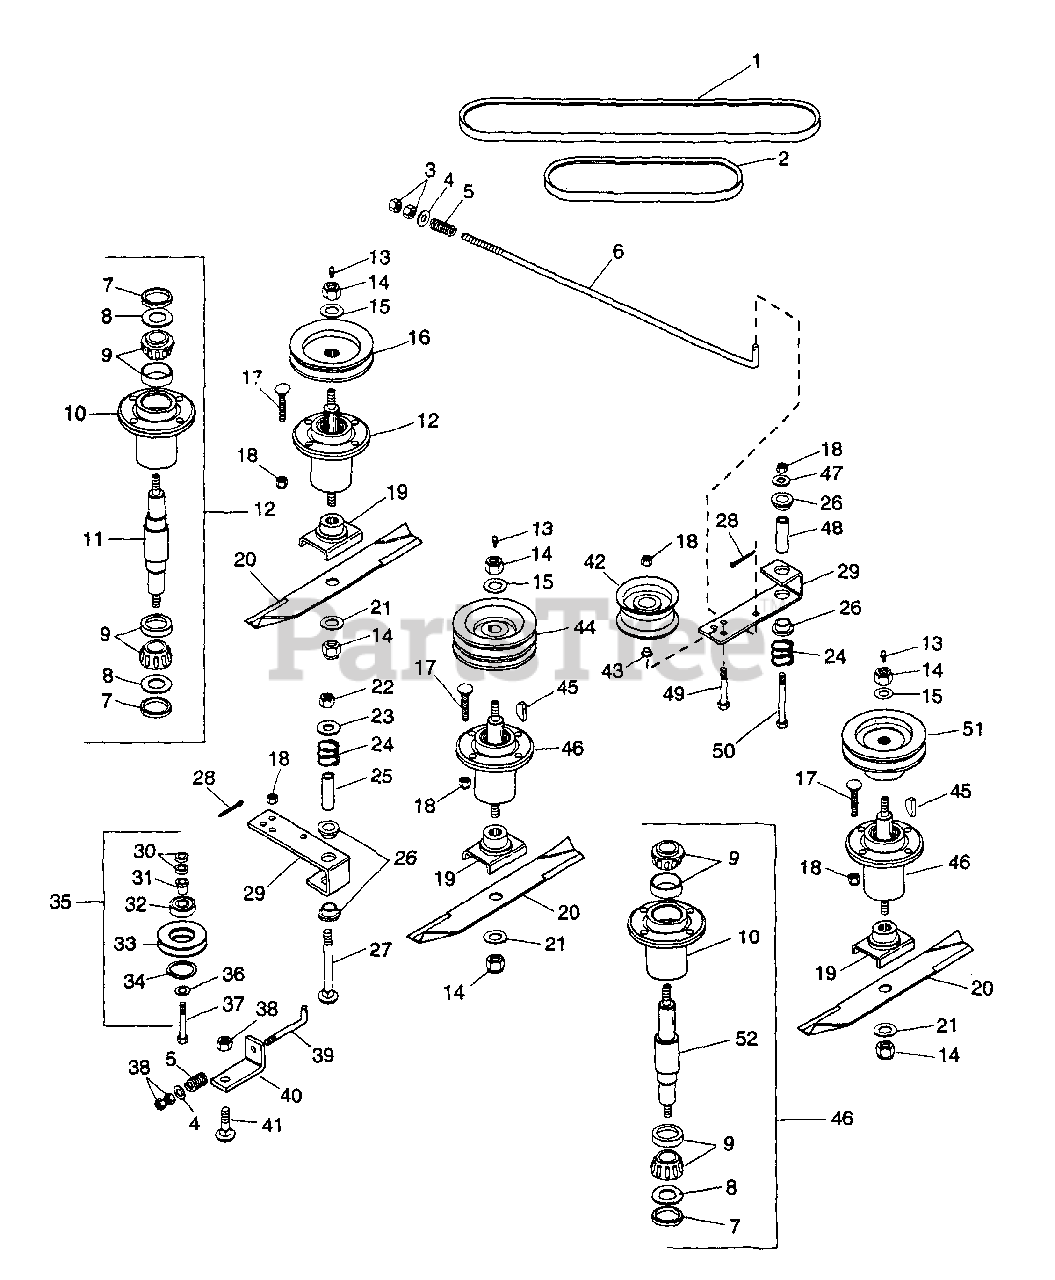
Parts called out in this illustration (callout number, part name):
1	V-Belt A-RMA 48.00 x .516/.031
2	V-Belt A-RMA 40.60 x .516/.031
3	Nut-Hex .375-16
4	Washer-Flat-Steel .281 x .625 x .065
5	Spring-Compression .188 x 1.66 x 2.0
6	Rod, Idler 25.0 Long
7	Seal-Steel
8	Washer-Flat-Steel .97 x 1.865 x .03
9	Assembly, Bearing Cup & Cone
10	Housing, Bearing
11	Shaft, Spindle
12	Spindle, Assembly
13	Fitting, Lube 1/8
14	Nut, Lock 5/8-11 Hex W/Insr
15	Washer-Flat-Steel .687 x 1.312 x .135
16	Sheave, Spindle
17	Bolt-Carriage .38-16 x 1.375
18	Nut-Lock-Nylon .375-16 Pl
19	Weldment, Blade Cradle
20	Blade
21	Washer-Flat-Steel .656 x 1.312 x .095 Pl
22	Nut-Lock .50-13 Hex Type N
23	Washer-Flat-Steel .531 x 1.250 x .100
24	Spring-Compression
25	Bushing, Steel .560 x .750 x 2.44
26	Bushing-Flange .762 x 1.0 x .580 x 1.48 NY
27	Bolt-Carriage .50-13 x 3.50
28	Pin-Cotter .09 x .75 Pl
29	Arm, Idler Pivot
30	Bushing .406 x .750 x .188
31	Bushing-Flange .786 x 1.0 x .79
32	Bearing-Ball 1.85 x .787 x .55
33	Sheave Idler
34	Snap Ring - Internal 2.054 x .062
35	Assembly, Idler Sheave
36	Washer, Flat .375 x 1.125 x .065
37	Bolt-Hex .38-16 x 2.00 Pl Gr. 5
38	Nut-Lock-Nylon .312-19 Pl
39	Rod, Idler
40	Bracket, Belt Tensioner
41	Bolt-Carriage .31-18 x 1.0
42	Idler-Flat 4-.687 x .38
43	Bushing-Flange .406 x .88 x .270 x .140
44	Sheave. Spindle (Center)
45	Key, Woodruff 1/4 x 1 Hard #15
46	Assembly, Spindle
47	Washer-Flat-Steel .438 x 1.00 x .083
48	Bushing, Steel .437 x .750 x 2.44 St
49	Bolt-Hex.38-16 x 2.25 Gr.5
50	Bolt-Hex .38-16 x 3.25 Pl Gr. 5
51	Sheave, Spindle (L.H.)
52	Shaft, Spindle
